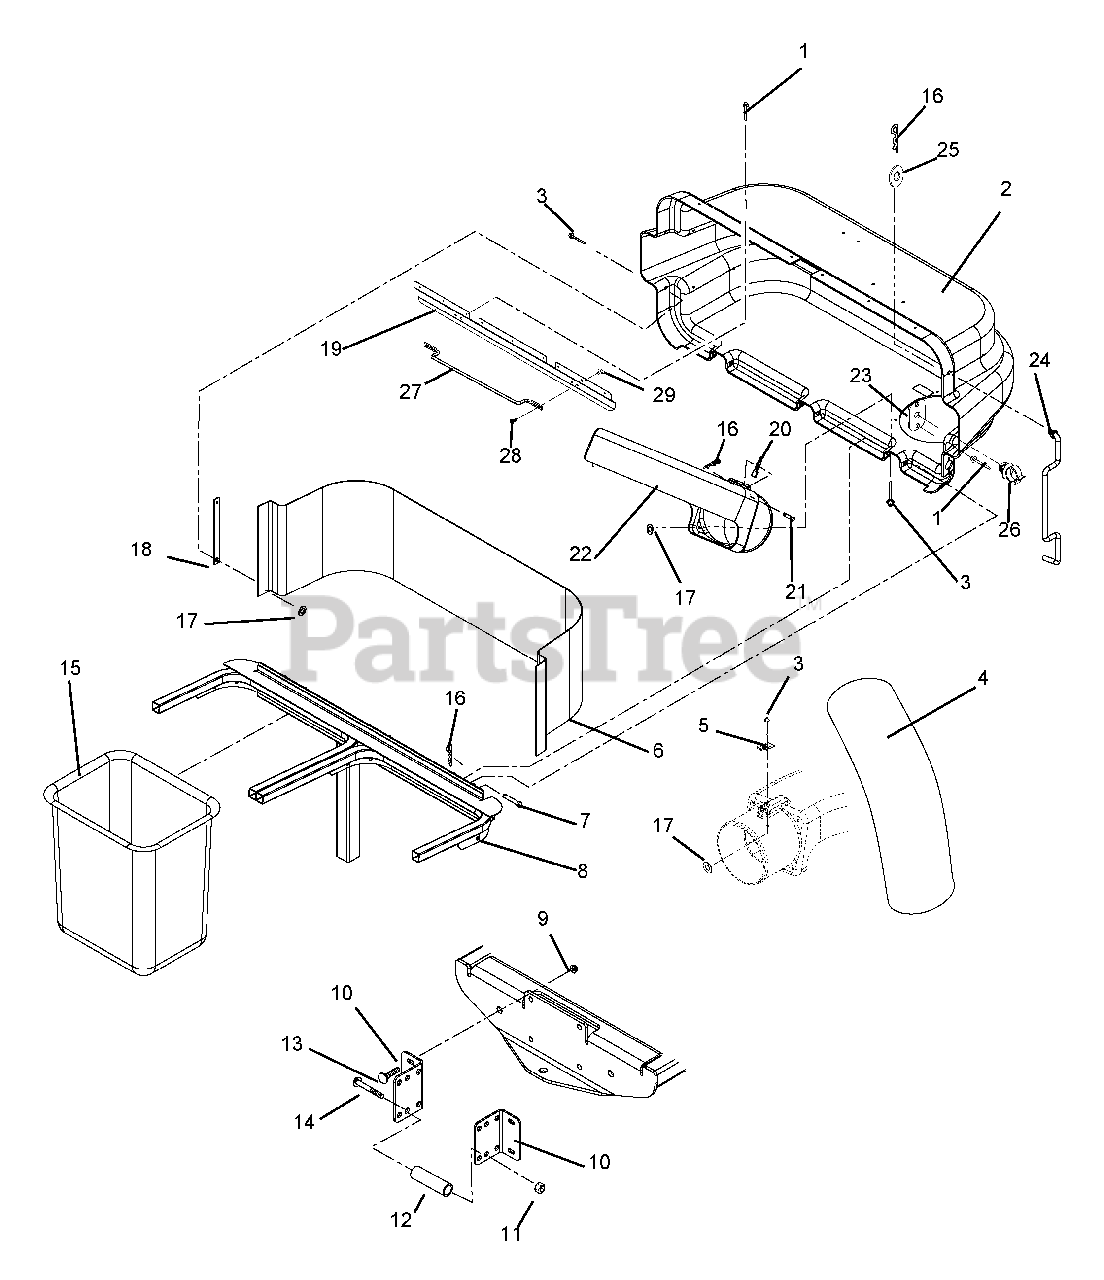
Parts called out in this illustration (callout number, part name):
1	RVT-POP .187X.402 DOME ST
2	BAGGER COVER W/DECAL
3	RVT-POP .187X.375
4	HOSE,7X38 KANAFLEX 165CL
5	THUMB LATCH
6	SCREEN, BAGGER
7	PIN-CLEV .371X3.25 YWZC
8	WMT,BAGGER FRAME
9	@NUT-LK-NYL-FLG .38-16 YWZC
10	BKT,BAGGER MOUNT
11	@NUT-LK-TOP-FLG .50-13 YWZC
12	SPACER, PIVOT .500X.750X1.805
13	@BLT-RDHDSQNK .38-16X1.25 G5YZ
14	@BLT-HEX .50-13X3.00 GR5 YWZC
15	GRASS BAGGER BASKET
16	PIN-HAIR, ENDRIES #25 YWZC
17	@WSHR-FL-STL.219X.50X.049 YWZC
18	STRAP,COVER
19	LATCH, BAGGER (MZ)
20	INDICATOR, FLOW
21	PIN-CLEV .309 X 1.625 YWZC
22	BOOT,UPPER
23	PLATE, ROD CLIP
24	PROP-ROD,BAGGER
25	@WSHR-FL-STL.406X.812X.065 YWZ
26	CLIP-.38
27	BAGGER HANDLE
28	@BLT-RDHDSQNK .25-20X.75 G5YZ
29	@NUT-LK-TOP-FLG .25-20 YWZC
